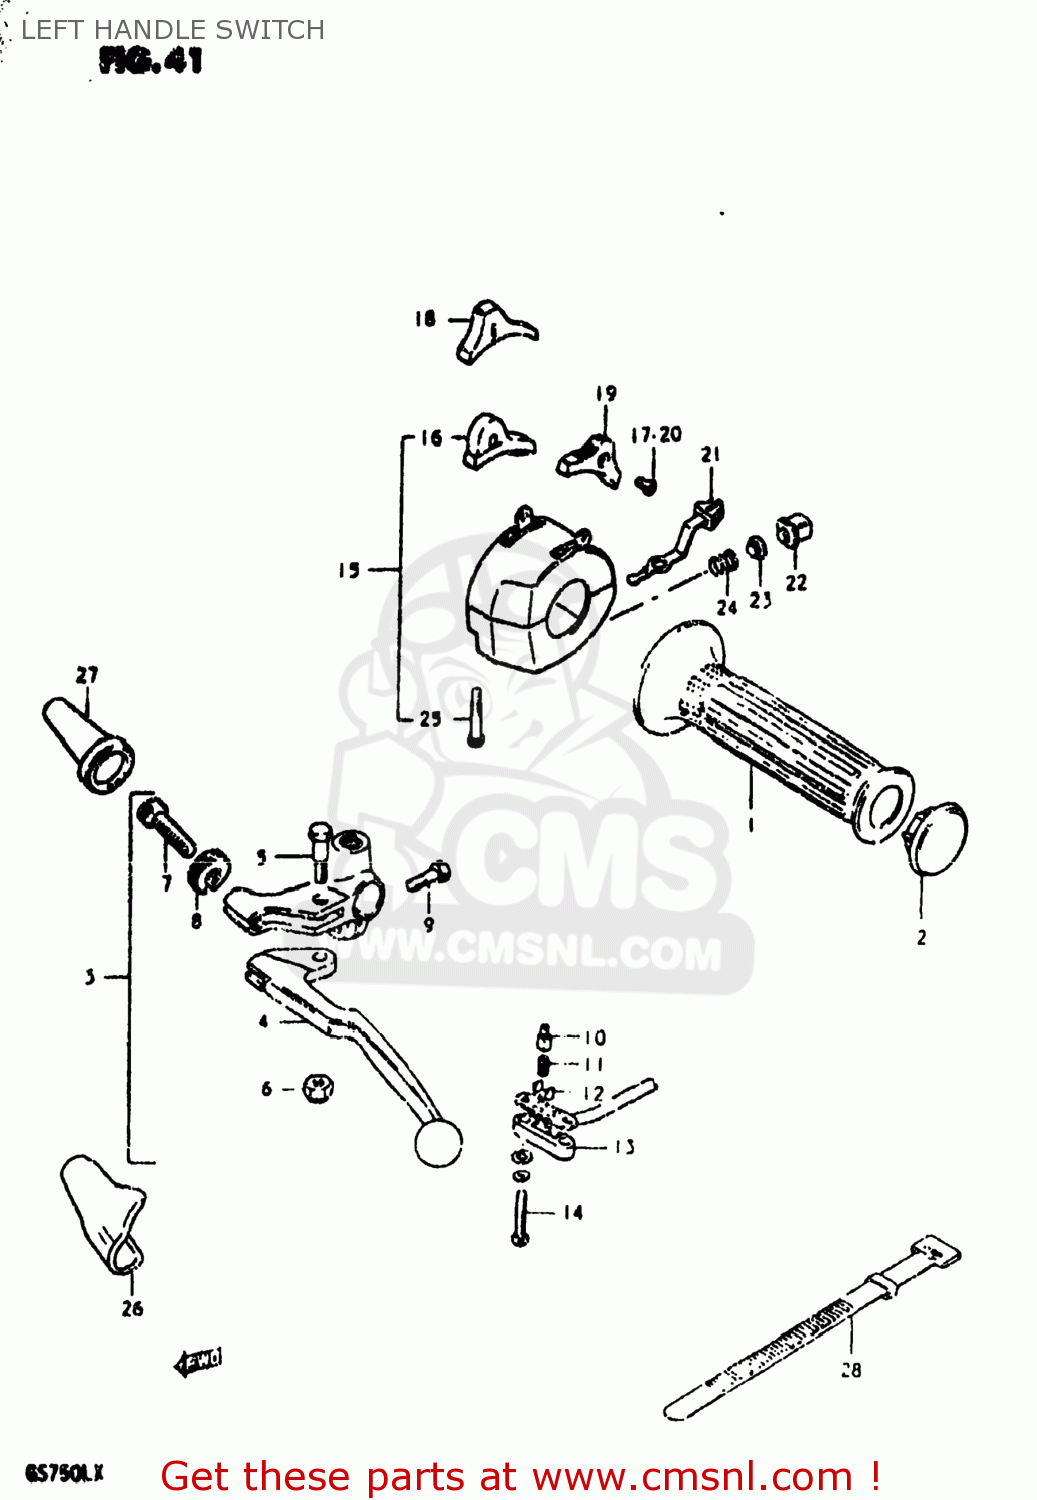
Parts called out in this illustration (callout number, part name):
1	GRIP,LEFT
2	CAP,GRIP END
3	LEVER ASSEMBLY
4	LEVER,CLUTCH
5	BOLT,LEVER
6	NUT 6MM
7	ADJUSTER,CABLE
8	NUT,CABLE ADJUSTER
9	BOLT,CLUTCH LEVER HOLDER
10	HOLDER
11	SPRING
12	PLATE
13	COVER,FR BK TERMINAL BASE
14	SCREW
15	SWITCH ASSY,HANDLE,L
16	KNOB,STOP
17	SCREW
18	KNOB,LIGHTING SWITCH
19	KNOB,DIMMER SWITCH
20	SCREW
21	KNOB,TURNSIGNAL
22	BUTTON,HORN
23	CONTACT
24	SPRING
25	SCREW
26	COVER,CLUTCH LEVER
27	BOOT,CLUTCH CABLE
28	CLAMP(L:120)
